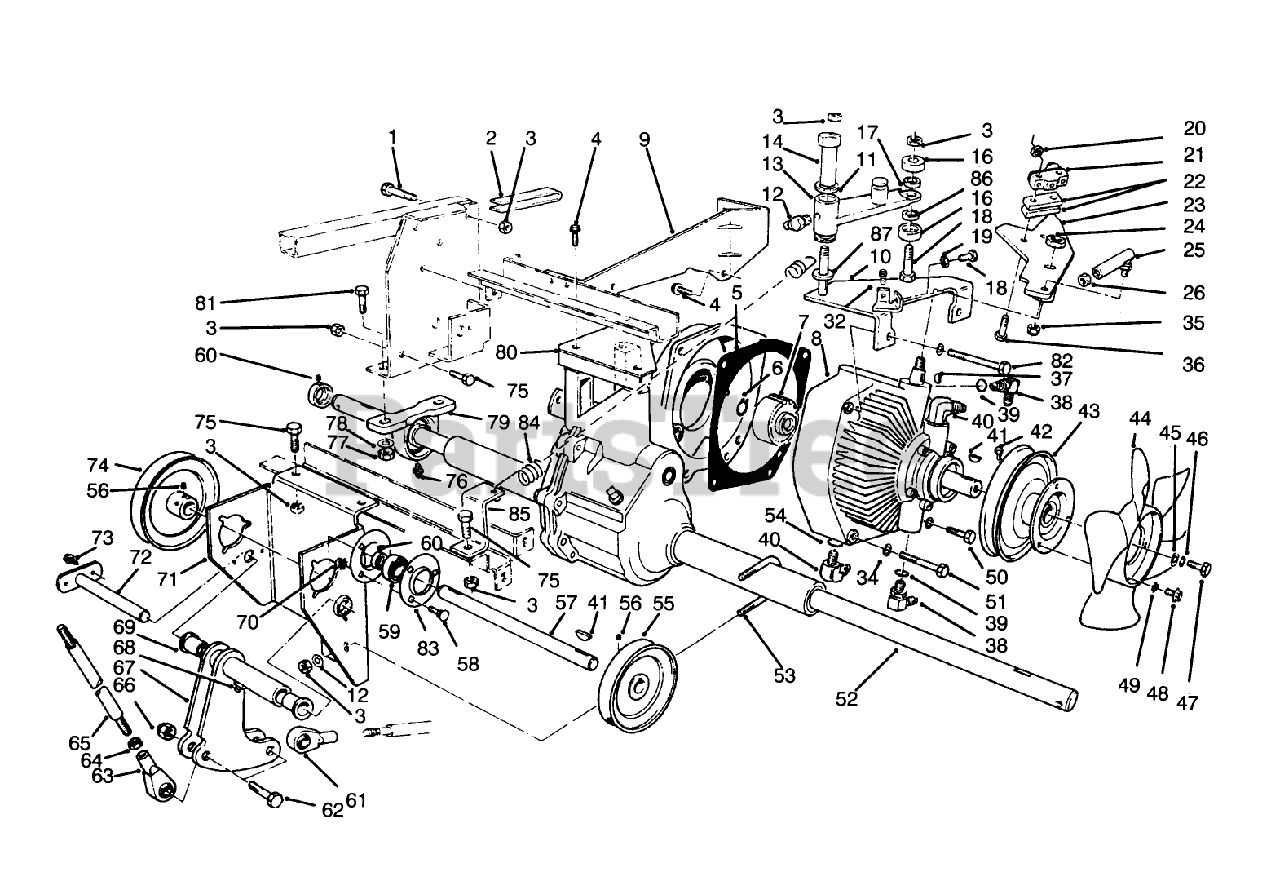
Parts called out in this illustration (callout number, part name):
1	SCREW-HH
2	TUBE SPACER
3	NUT-LOCK, NI
4	SCREW-HHF
5	TRANS GASKET
6	RING-SNAP, EXTERNAL
7	GEAR-SPUR
8	HYDROSTATIC TRANS.
9	Bracket-Transaxle
10	Plate-Traction
11	WASHER-THRUST
12	FITTING-GREASE, 90 DEG
13	NEUTRAL SWITCH ARM ASSY
14	STUD-TRACTION
16	BEARING-BALL
17	SPACER-BEARING
18	SCREW-HH
19	NUT-HEX
20	NUT-HEX
21	SWITCH-MICRO
22	PLATE-SWITCH
23	Lever-Traction
24	NUT-LOCK, NI
25	JOINT-BALL
26	NUT-JAM
32	SCREW-HH
35	NUT-LOCK
36	SCREW-PPH
37	KEY-WOODRUFF
38	Fitting-Hydraulic 90deg. (Incl. Ref. #39)
39	O-RING
40	Fitting-Hydraulic 90deg. (Incl. Ref. #54)
41	KEY-WOODRUFF
42	SCREW-SQH
43	TRANS PULLEY
44	FAN 8"
45	WASHER-FLAT
46	WASHER-LOCK
47	SCREW-HH
48	SCREW-SHWH
49	WASHER-LOCK/EXT
50	SCREW-HH
51	SCREW-HH
52	Differential Assembly
53	U-BOLT
54	O-RING
55	JACKSHAFT INPUT PULLEY
56	SCREW-SET, SQH
57	JACKSHAFT
58	BOLT-CARR
59	BEARING-BALL
60	SCREW-SET, HSH
61	BALL JOINT LH
62	SCREW-HH
63	BALL JOINT RH
64	NUT-JAM
65	Rod-Steering
66	NUT-HEX
67	Bellcrank Assembly (Incl. Ref. #68 & 69)
68	GREASE FITTING
69	BUSHING PM
70	NUT-KEPS
71	Bracket-Jackshaft
72	Shaft-Bellcrank
73	SCREW-HHFTF
74	JACKSHAFT OUTPUT PULLEY
75	SCREW-HH
76	FITTING-GREASE
77	Nut-Lock
78	WASHER-FLAT
79	BEARING - PILLOW BLOCK
80	TRANSAXLE PLATE
81	SCREW-HH
82	SCREW-HH
83	FLANGE
84	SPRING-EXTENSION
85	Bracket-Spring
86	SPACER
87	WASHER-FLAT
